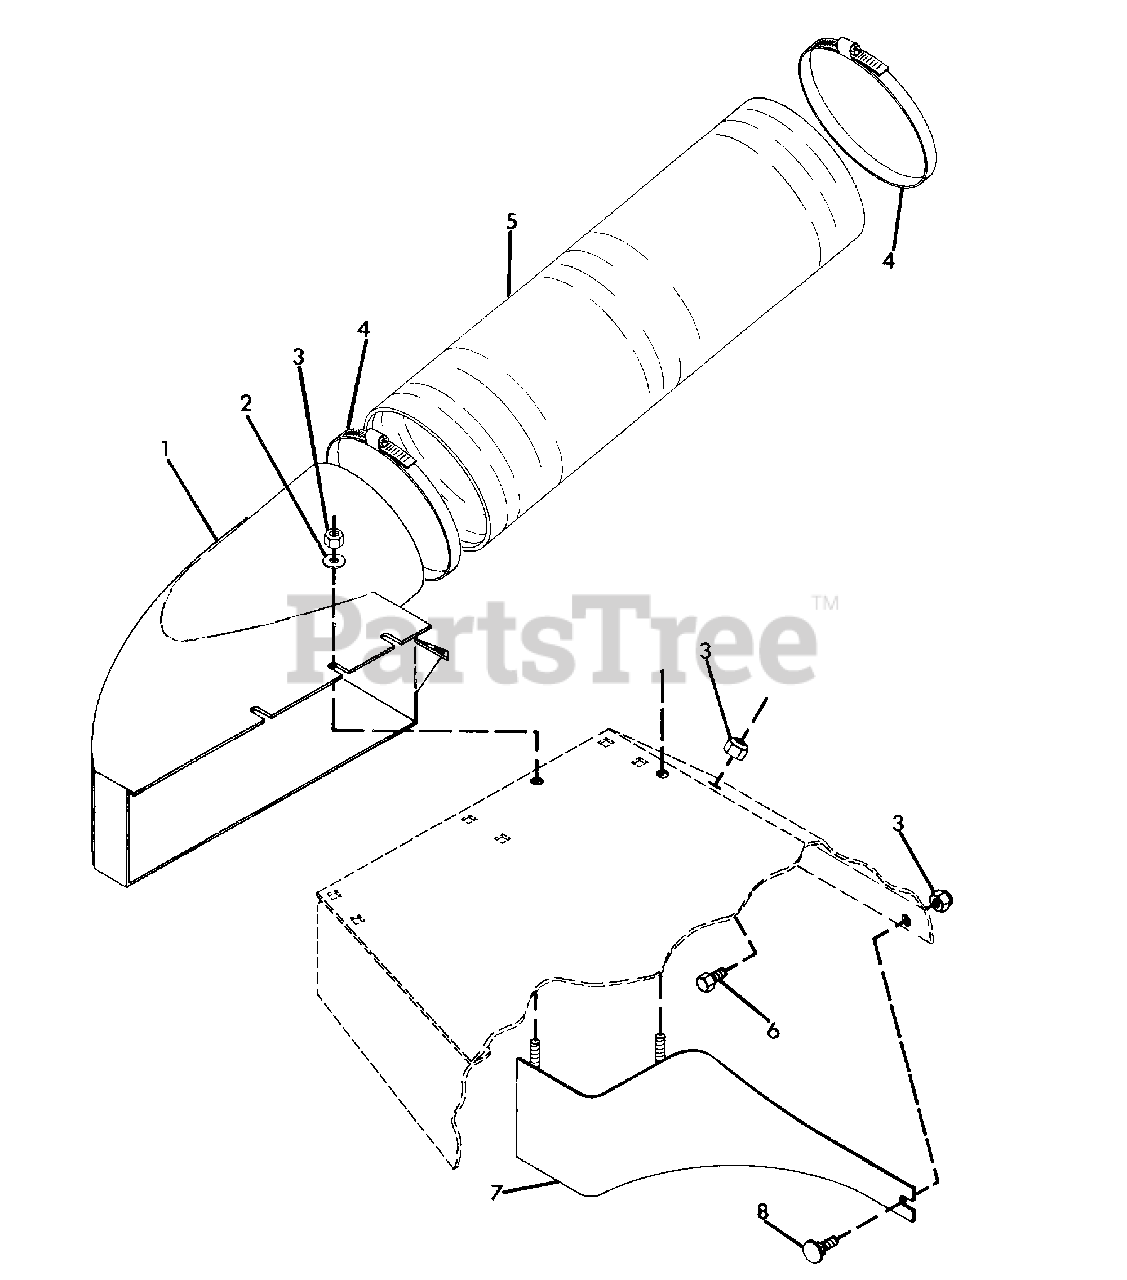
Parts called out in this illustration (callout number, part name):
1	CHUTE, 60" DISCHARGE
2	WASHER, FLAT .406X.812X.065
3	NUT, LOCK 3/8-16
4	CLAMP
5	HOSE, MOWER TO BLOWER
6	BOLT, HEX 3/8-16X1
7	WELDMENT, BAFFLE
8	BOLT, CARRIAGE 3/8-16X.75
